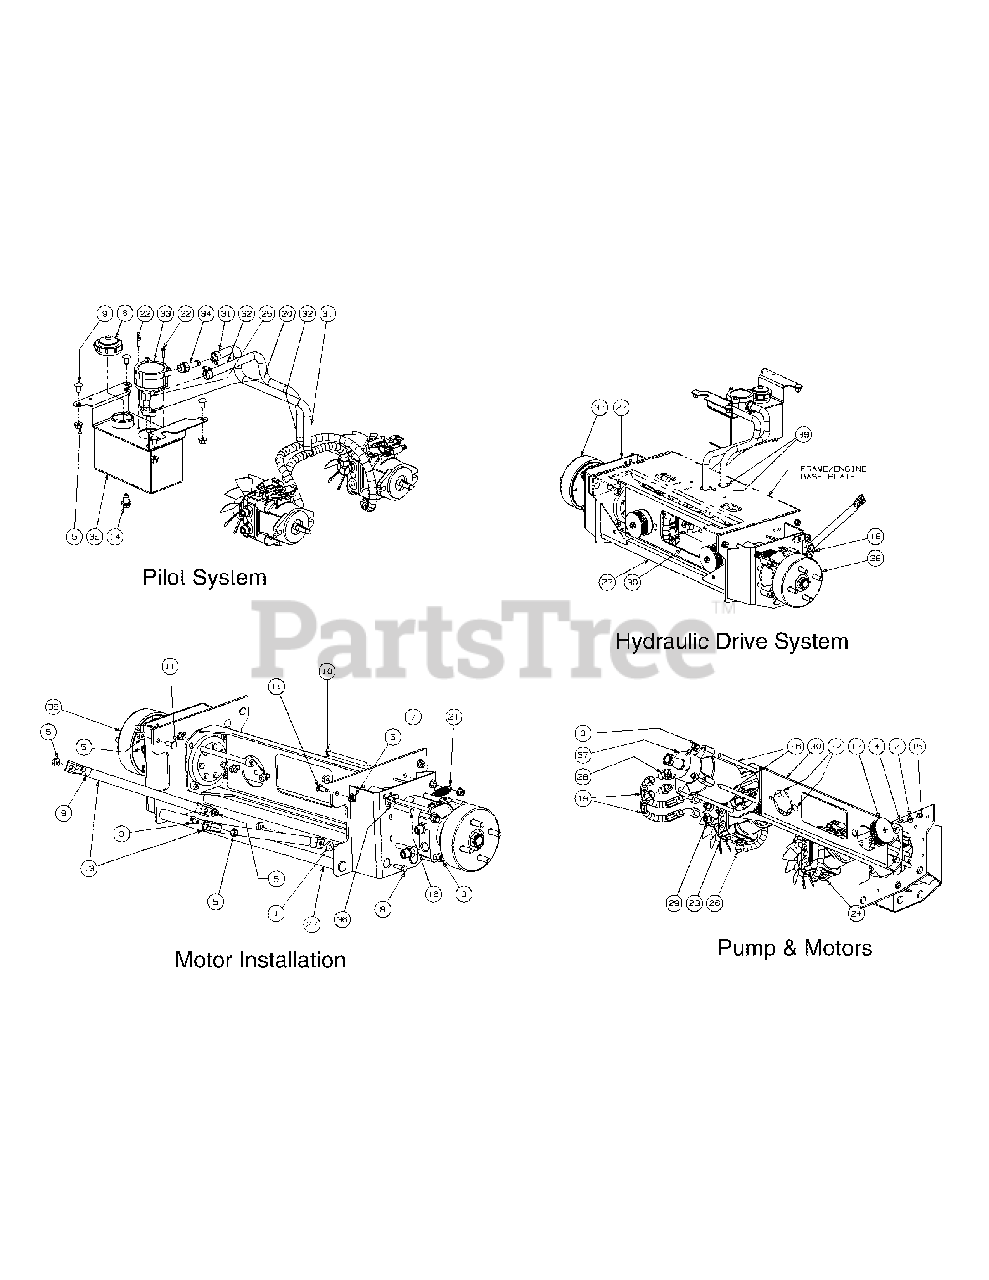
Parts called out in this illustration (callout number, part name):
1	Idler Washer
2	Flat Washer, 3/8
3	Washer lock 3/8 zinc
4	Key, 3/16" x 7/8"
5	Flange Lock Hex Nut, 3/8-16
6	Cap, Hydro Oil Tank
7	Hex Cap Screw, 3/8-16 x 4.50
8	Hex Cap Screw, 3/8 -16 x 1.25
9	Carriage Bolt, 3/8-16 x .75 LG.
10	Carriage Bolt, 3/8-16 x 5.00
11	Carriage Bolt, 3/8-16 x 1
12	Carriage Screw, 3/8-16 x 1.25
15	Hex Nut, 3/8-24
16	Socket Head Capscrew, 1/2-13; 6-1/2
17	Hydro Pulley Pump
18	Hose Assembly, RH
19	Hose Assembly, LH
20	Grommet Fitting, .54 ID x .78 OD
21	Spring Extension, .740 OD x 2.656
22	Socket Low Head Cap Screw, 1/4-20 x 0.75
23	Hydro Pump, BDP-12, LH
24	Hydro Pump, BDP-12, RH
25	Fitting Elbow Spur, 5/8 x 1/2
26	Fitting Elbow, 9/16 x 1/2
27	Hydro Motor Frame Assembly
28	Adaptor Fitting, 8 x 10
29	Adaptor Fitting, 8 x 8
30	Hydro Pump Mounting Bracket
31	Hose Assembly, Pilot includes:
32	Hose Assembly, Drain includes:
33	Hydraulic In-Tank Filter includes:
33	Filter Element
34	Fitting, 3/4 ORB x 1/2 Tube
35	Hydraulic Tank Assembly
36	Rear Cable Mounting Bracket
37	Hydro Motor, Left Hand Assembly w/ Brake & Drum
38	Hydro Motor, Right Hand Assembly w/ Brake & Drum
39	Gromment, .75 ID
